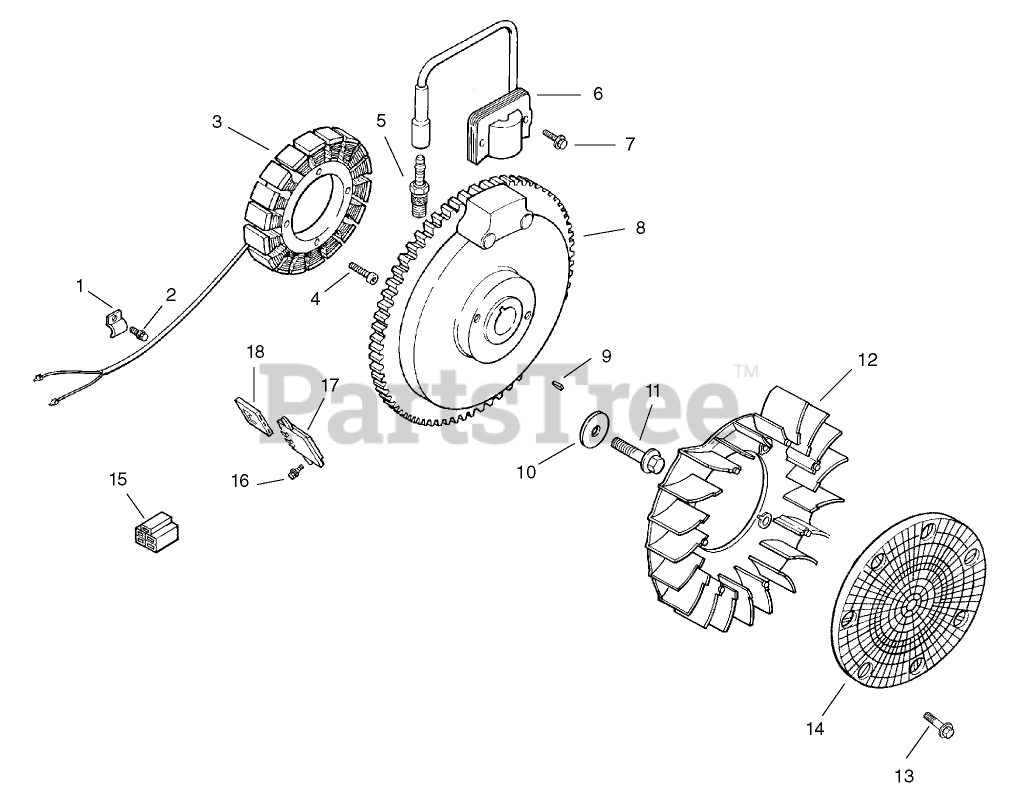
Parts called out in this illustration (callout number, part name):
1	Clip
2	SCREW-HHFTF (M5X.80X10)
3	Kit, Stator (Incl. Terminal 25 452 01-S)
4	SCREW-THREAD FORMING (M5X0.8X25)
5	SPARK PLUG
6	Module-Ignition
7	SCREW-FLANGE, THREAD FORMING (M5X.8X20)
8	Flywheel
9	KEY (3/16 X 5/8)
10	WASHER-FLAT (13/32)
11	SCREW-FLANGE (M10X1.5X45)
12	Fan
13	BOLT-SHOULDER (M6x1.0x16)
14	Screen-Grass
15	Connector (5 contact)
16	Screw-HF (M6x1.0x16)
17	Rectifier-Regulator
18	Connector (3 contact)
